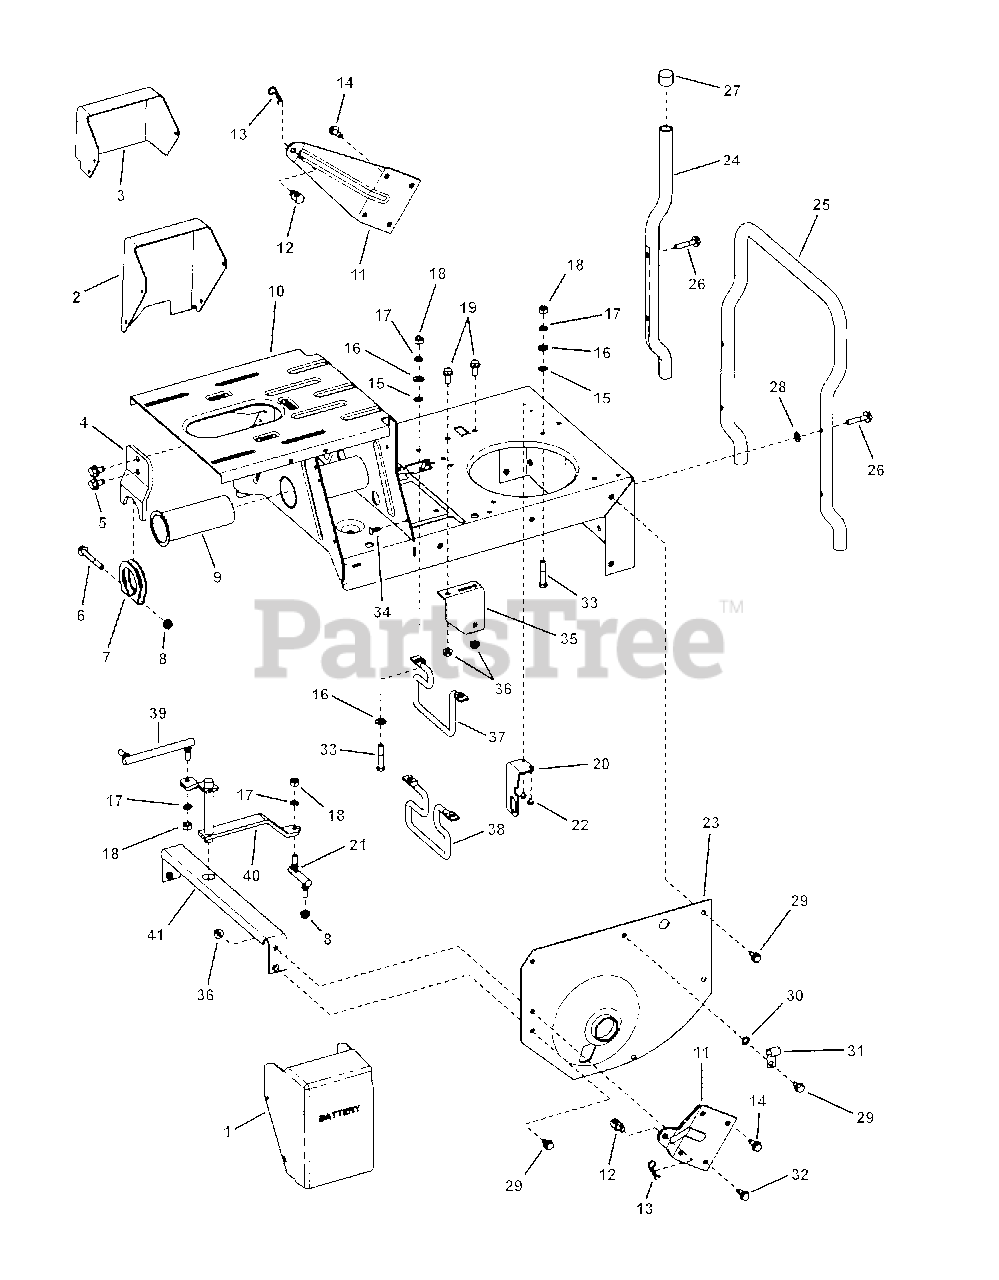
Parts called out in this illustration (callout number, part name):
1	COVER, Battery
2	COVER, Switch
3	COVER, Solenoid
4	BRACKET, Belt Adjuster
5	SCREW, 3/8-16 x 5/8" Hex Washer Self-Tap
6	SCREW, 5/16-24 x 2-1/2" Hex Head Cap, GR 5
7	TUBE CLAMP
8	NUT, 5/16-24 Flange Lock (Large)
9	BUSHING, Pivot
10	WELDMENT, Main Case (Standard)
11	WING, Rear
12	SWIVEL, Adjustable
13	HAIR PIN, 3/32 x 1-1/2"
14	SCREW, 5/16-18 x 3/4" Hex Washer Self-Tap
15	RETAINER, 5/16" Bolt
16	WASHER, 5/16" Flat
17	WASHER, .32 x .58 x .08 Split Lock
18	NUT, 5/16-24 Hex, GR 5
19	BOLT, 5/16-18 x 3/4" Hex Flange Lock, GR 5
20	BRACKET, Switch
21	SHIFT LINK, Short (5/16-24 thread)
22	SCREW, #10-32 x 1/4" Hex Washer Self-Tap
23	FENDER, Left Hand (1.628" I. D. Hole)
24	BUMPER, Rear
25	BUMPER (1-Piece) (33" Deck)
26	SCREW, 5/16-18 x 1-1/2" Hex Washer Self-Tap
27	CAP, Bumper
28	WASHER, 11/32" Flat
29	SCREW, 5/16-18 x 5/8" Hex Washer Self-Tap
30	WASHER, 5/16" Internal Tooth Lock
31	CLIP, Wire
32	SCREW, 5/16-18 x 3/4" Hex Head Cap, GR 5
33	SCREW, 5/16-24 x 1-3/4" Hex Head Cap, GR 5
34	FASTENER, 1/4" Ratchet
35	BRACKET, Drive Support
36	NUT, 5/16-18 Hex Flange Lock, GR 5
37	BELT GUIDE, 25, 26, 28, 41" (5.74" Bolt Pattern, 4.74" Belt Gap)
38	BELT GUIDE, 30/33 (5.74" Bolt Pattern, 5.0" Belt Gap)
39	SHIFT LINK, Long (5/16-24 both ends)
40	WELDMENT, Shift Arm
41	CROSS BRACE
